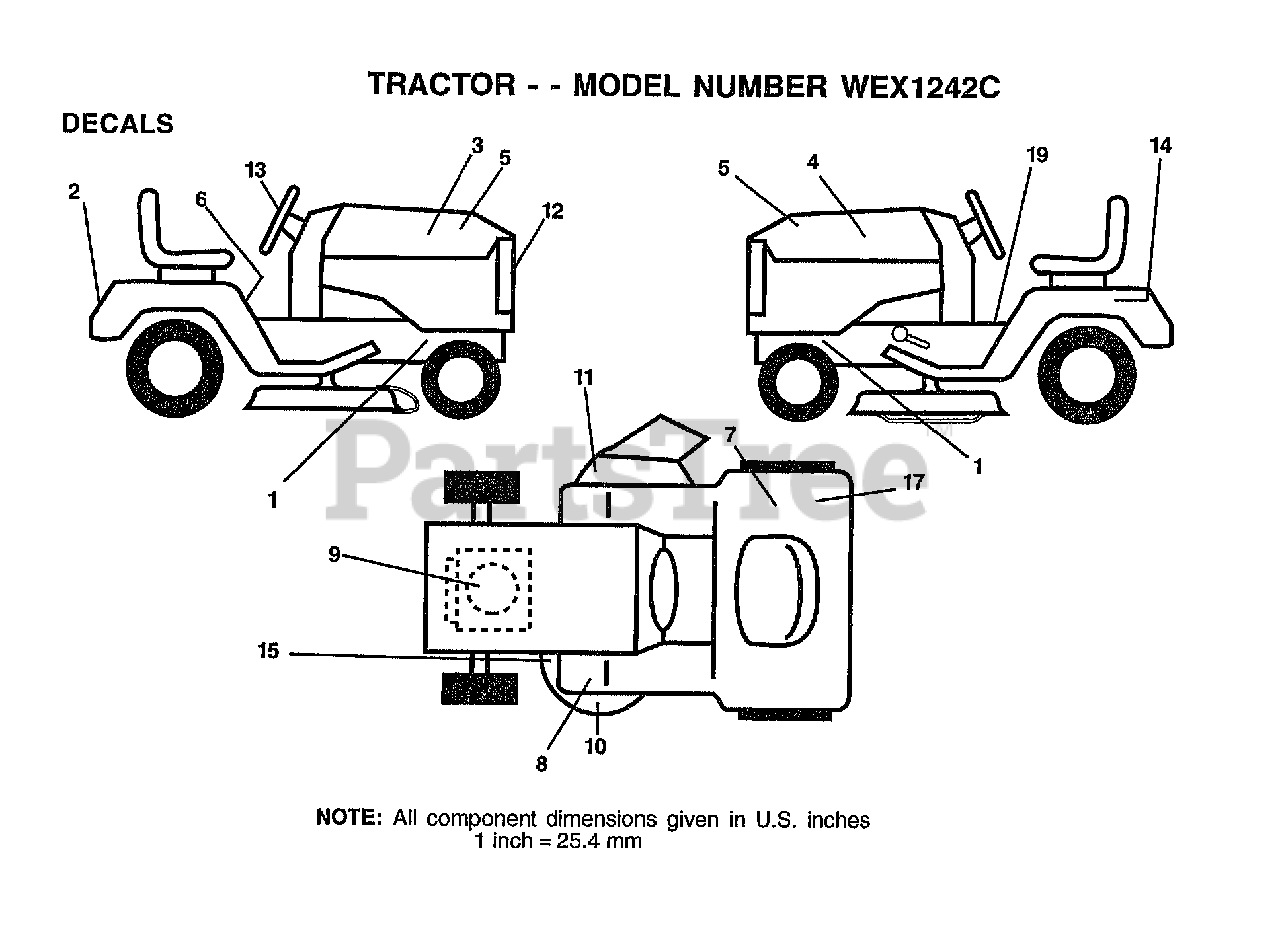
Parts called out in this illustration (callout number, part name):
1	"DECAL CHASSIS,HOT"
2	DECAL, FENDER
3	DECAL.HOOD.RH
4	DECAL.HOOD.LH
5	DECAL.PANEL.SD
6	DECAL.READ.O.MANU
7	DECAL.EURO.ST.CE.
8	DECAL-BRAKE/CLUTC
9	DECAL, ENGINE
10	DECAL, DECK GRASSEATER
11	DECAL.DANGER.CUTF
12	DECAL, GRILLE LENS
13	DECAL, INS STRG WH
14	DECAL.BATRY.3-3908
15	"DECAL-SCHEM,BELT"
19	DECAL BRAK PARK
